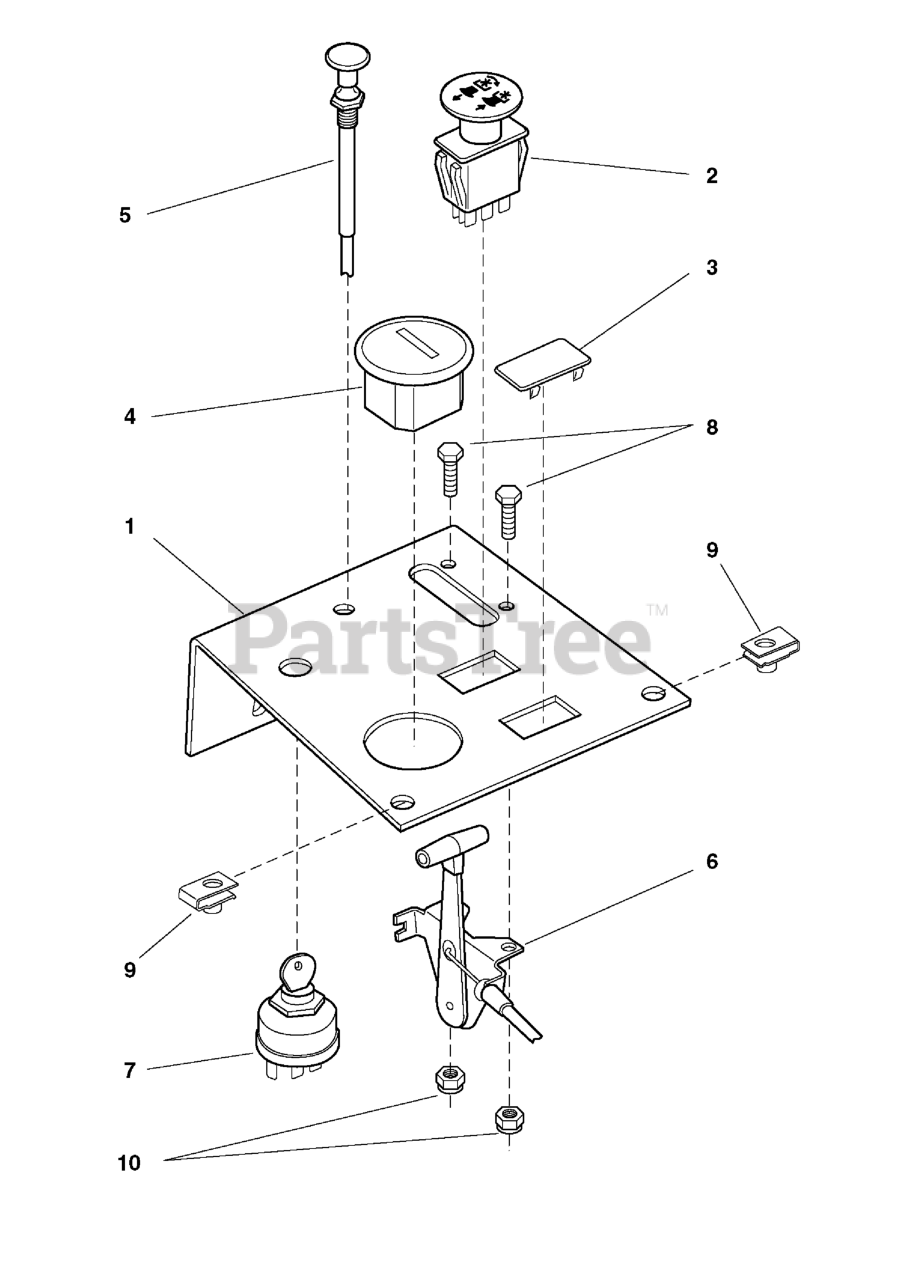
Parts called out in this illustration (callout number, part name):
1	PANEL, Instrument
2	SWITCH, BLADE ENGAGEMENT
3	HOLE PLUG
4	HOUR METER
5	CABLE, Choke Control, 57"
5	CABLE, CHOKE CONTROL, 45
6	CABLE, Throttle, 54"
7	SWITCH, IGNITION, 6 POST
8	BOLT, 1/4-20 x 3/4
9	BODY CLIP, 5/16-18-7GA MATERIAL
10	NUT, 1/4-20 HEX SERR. FLANGE
